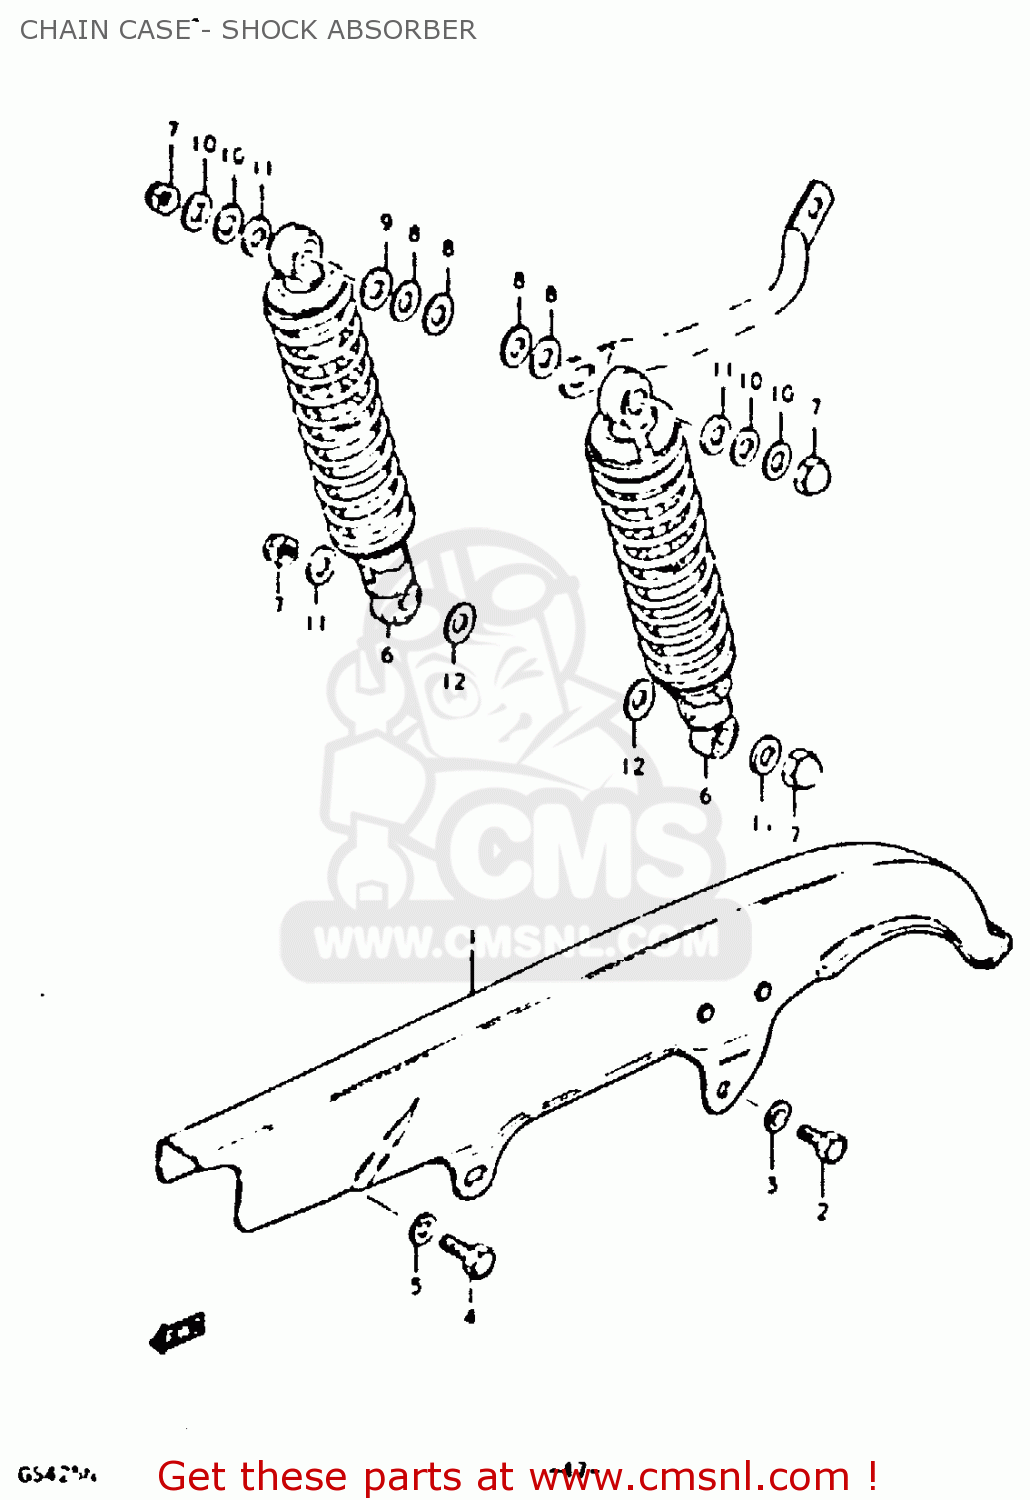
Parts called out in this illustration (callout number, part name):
1	CASE,CHAIN
2	BOLT(6X8)
3	WASHER
4	BOLT
5	WASHER(5.5X10X0.8)
6	ABSORBER ASSEMBLY,REAR SHOCK
7	NUT, LOWER LH
8	WASHER
9	WASHER (12.5X24X3.2)
10	WASHER
11	WASHER(10.5X24X3.2)
12	WASHER (12.5X24X1.6)
